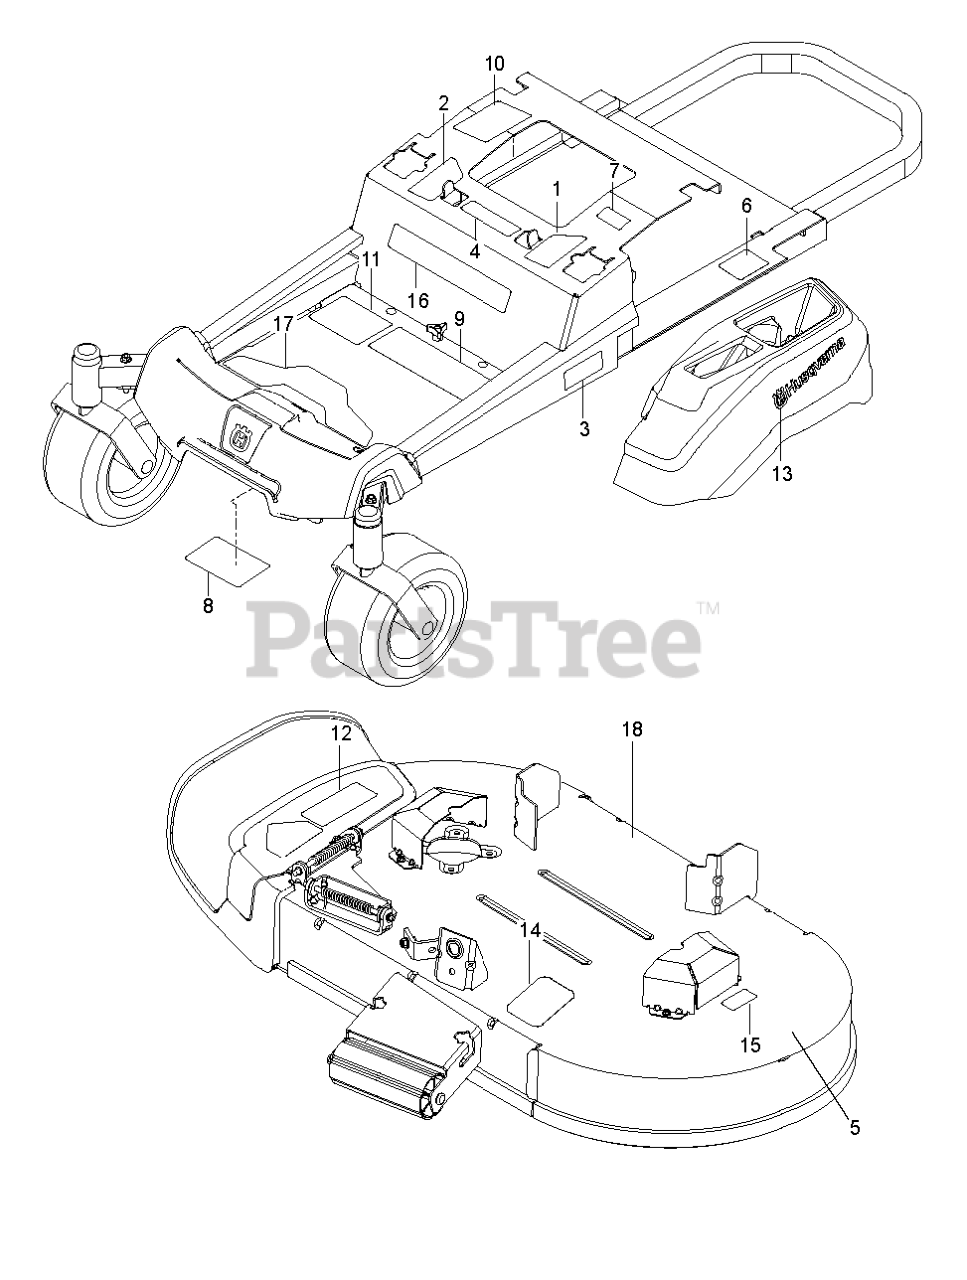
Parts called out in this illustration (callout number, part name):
1	DECAL.ZTR.RZ.THRTL/PRKBRK.V2.L
2	DECAL.ZTR.RZ.THRTL/PRKBRK.V2.R
3	DECAL.ZTR.SIDRAIL.Z242F.HUS
4	EURO DECAL-BATTERY WARNIN6
5	DECAL DECK DECAL DECAL.42DECK.
6	DECAL, DO NOT TOW
7	DECAL, EXITING MOWER
8	DECAL, SERVICE
9	DECAL ZTR WARNING DECAL DECAL.
10	DECAL.WARNING.CUST.RESP.E85.
11	DECAL.ZTR.STARTINSTRCT.CHOKE15
12	DECAL.TRACT/ZTR.DECKWARN.HUSQ
13	DECAL.HUSQVARNA.210MM
14	DECAL, BELT ROUTING
15	DECAL.DECK.CLEARCUT.NOSTEP
16	DECAL ZTR BRAND GRAPHIC DECAL.
17	PAD.RZ.FOOTREST.PLATE
18	DECAL DECK DECAL DECAL.DECK.WA
